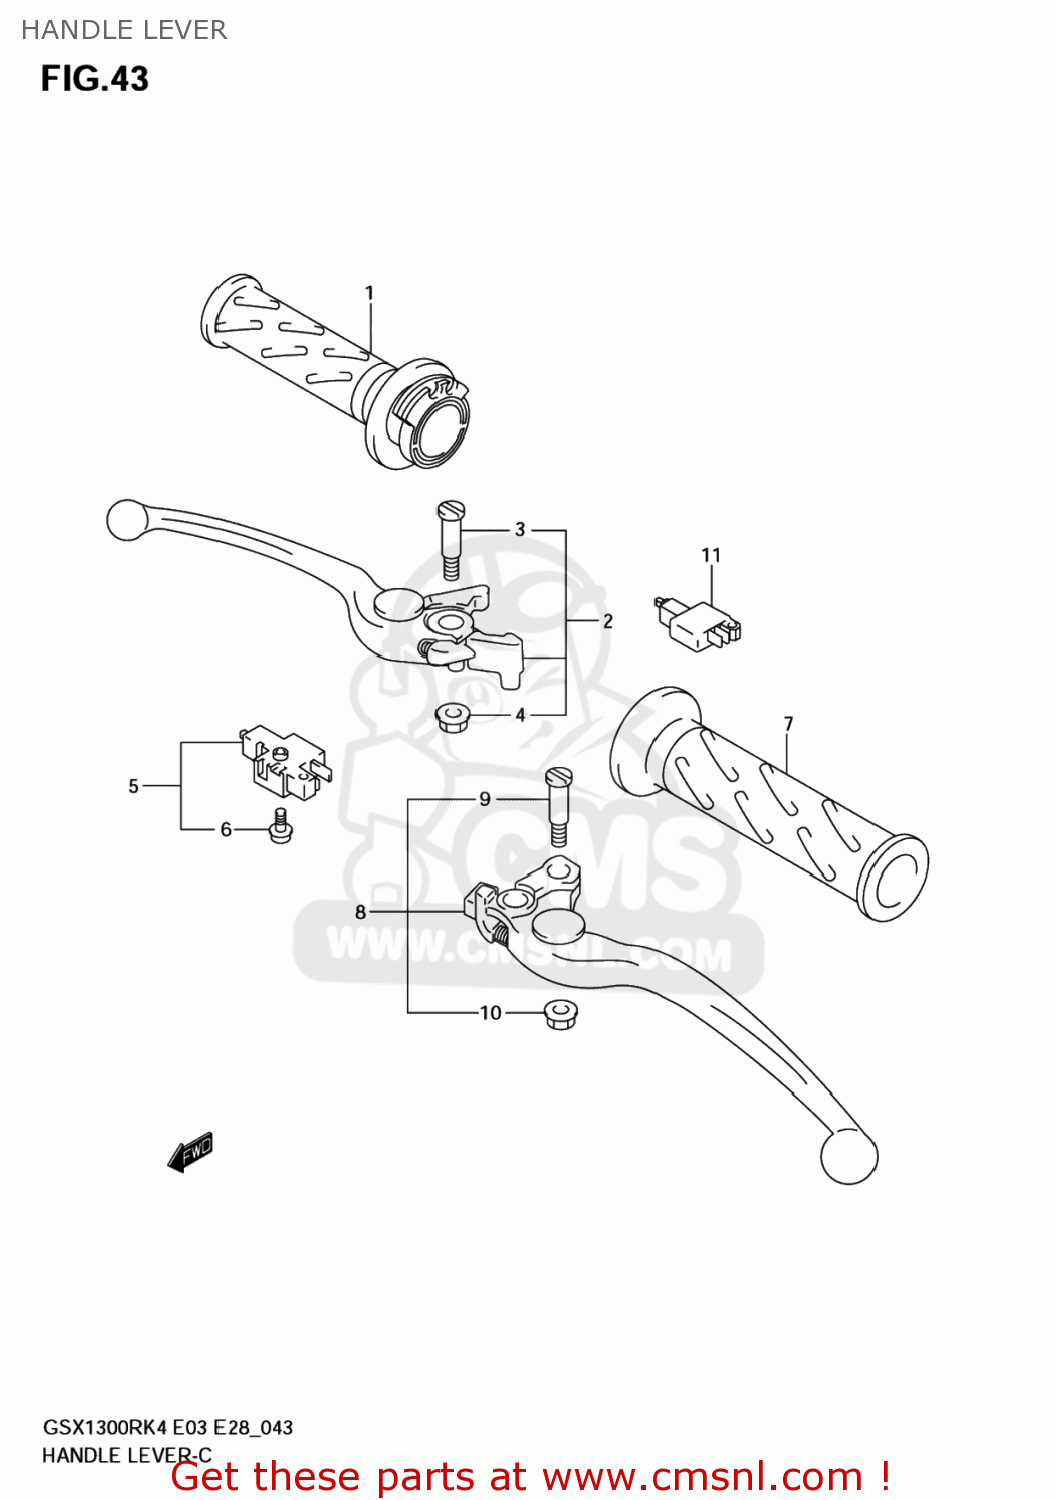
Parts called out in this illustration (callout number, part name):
1	GRIP,THROTTLE
2	LEVER ASSY,BRAKE
3	BOLT,LEVER PIVOT
4	NUT
5	SWITCH ASSY,ST
6	SCREW
7	GRIP,LEFT
8	LEVER ASSEMBLY,CLUTCH
9	BOLT,LEVER PIVOT
10	NUT
11	SWITCH ASSY,CLUTCH
